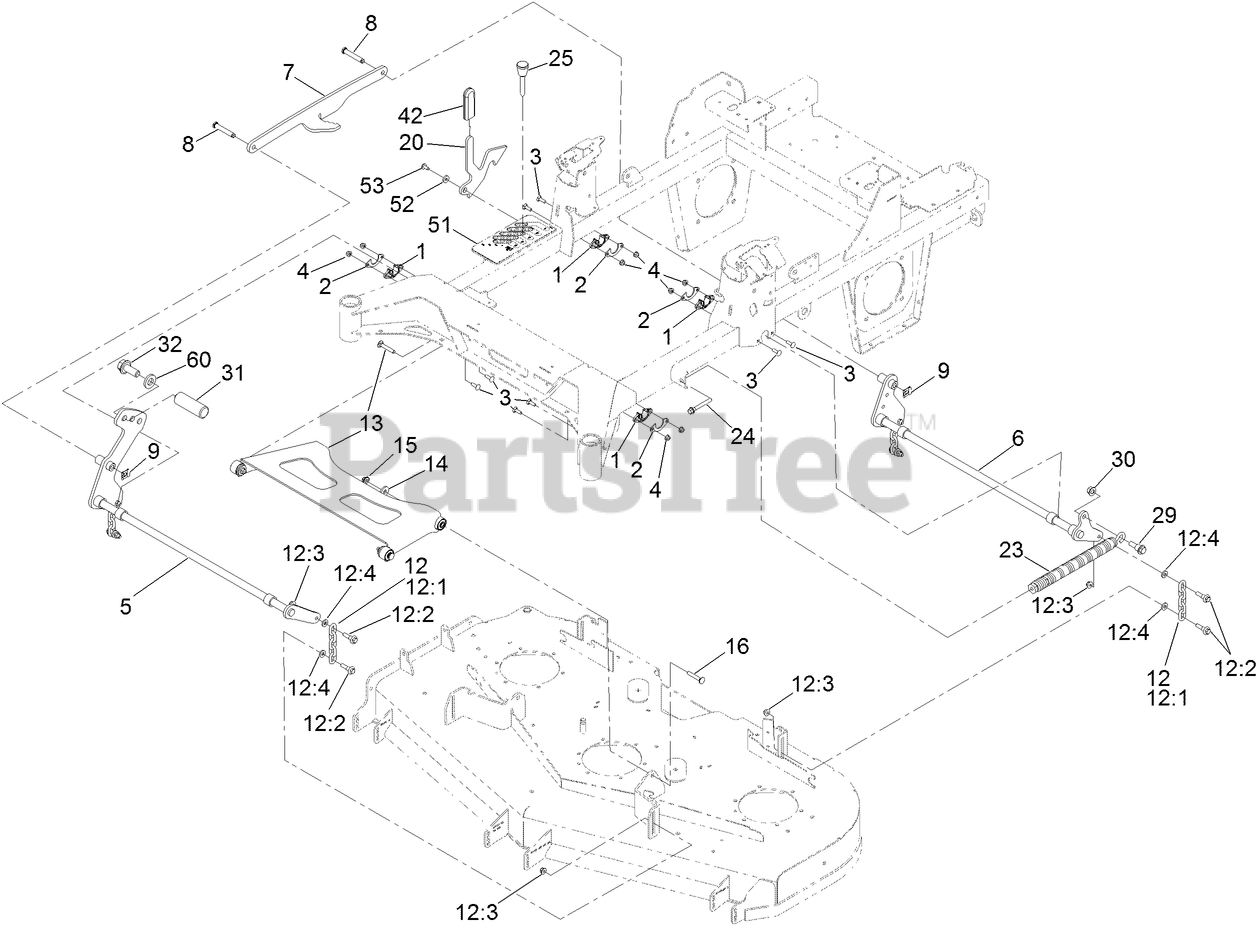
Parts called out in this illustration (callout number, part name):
1	BUSHING-FLANGE
2	GUSSET-LIFT, DECK
3	SCREW-CARR
4	NUT-HF, NI
5	DECK LIFT SHAFT ASM, FRT [BLACK
6	DECK LIFT SHAFT ASM [BLACK]
7	LINK-LIFT
8	PIN-CLEVIS
9	CLIP-PIN
12	DECK CHAIN ASM
12:1	CHAIN-LIFT, DECK
12:2	BOLT-SHOULDER
12:3	NUT-HF, NI
12:4	SPACER
13	ASM-DECK STRUT W/ BUSHINGS
14	WASHER
15	NUT-FLANGE, NI
16	SCREW-CARR
20	PLATE-TRANSPORT LOCK
23	SPRING-EXTENSION
24	BOLT-SHOULDER
25	PIN-HOC
29	SCREW-SHOULDER, HHF
30	NUT-LOCK
31	PEDAL-FOOT LIFT
32	SCREW-HHF
42	GRIP-LEVER
51	DECAL-HOC
52	SPACER
53	SCREW
60	WASHER
